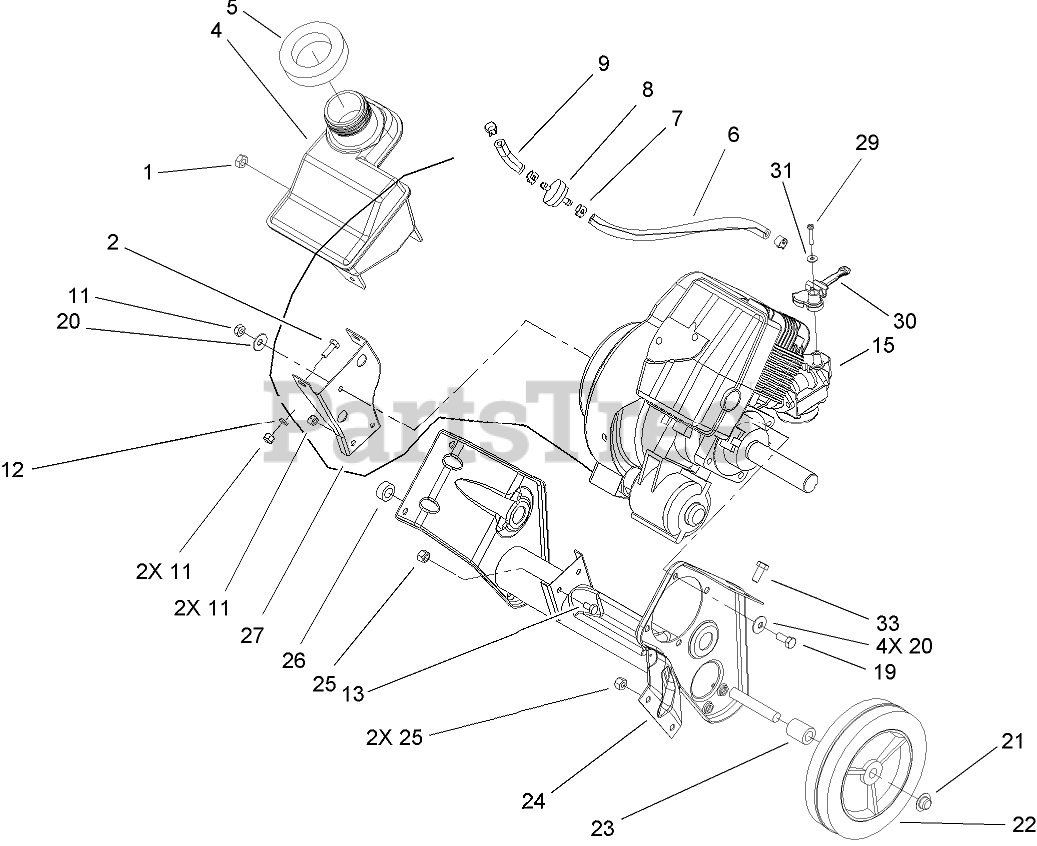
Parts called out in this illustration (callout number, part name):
1	NUT-LOCK, CONE
2	SCREW-HH
4	Tank-Gas
5	SEAL-FOAM
6	LINE-FUEL
7	CLAMP-HOSE
8	FILTER-FUEL
9	HOSE-FUEL
11	NUT-LOCK, NI
12	WASHER-FLAT
13	SCREW-HH
19	SCREW-HH
20	WASHER-BELLEVILLE
21	NUT-PUSH
22	WHEEL
23	SPACER-WHEEL
25	NUT-LOCK, NI
26	SPACER-WHEEL
27	BRACKET-SUPPORT, RECOIL
29	SCREW-PPH, PLASTITE
30	LEVER-CHOKE
31	WASHER-FLAT
33	SCREW-HH
